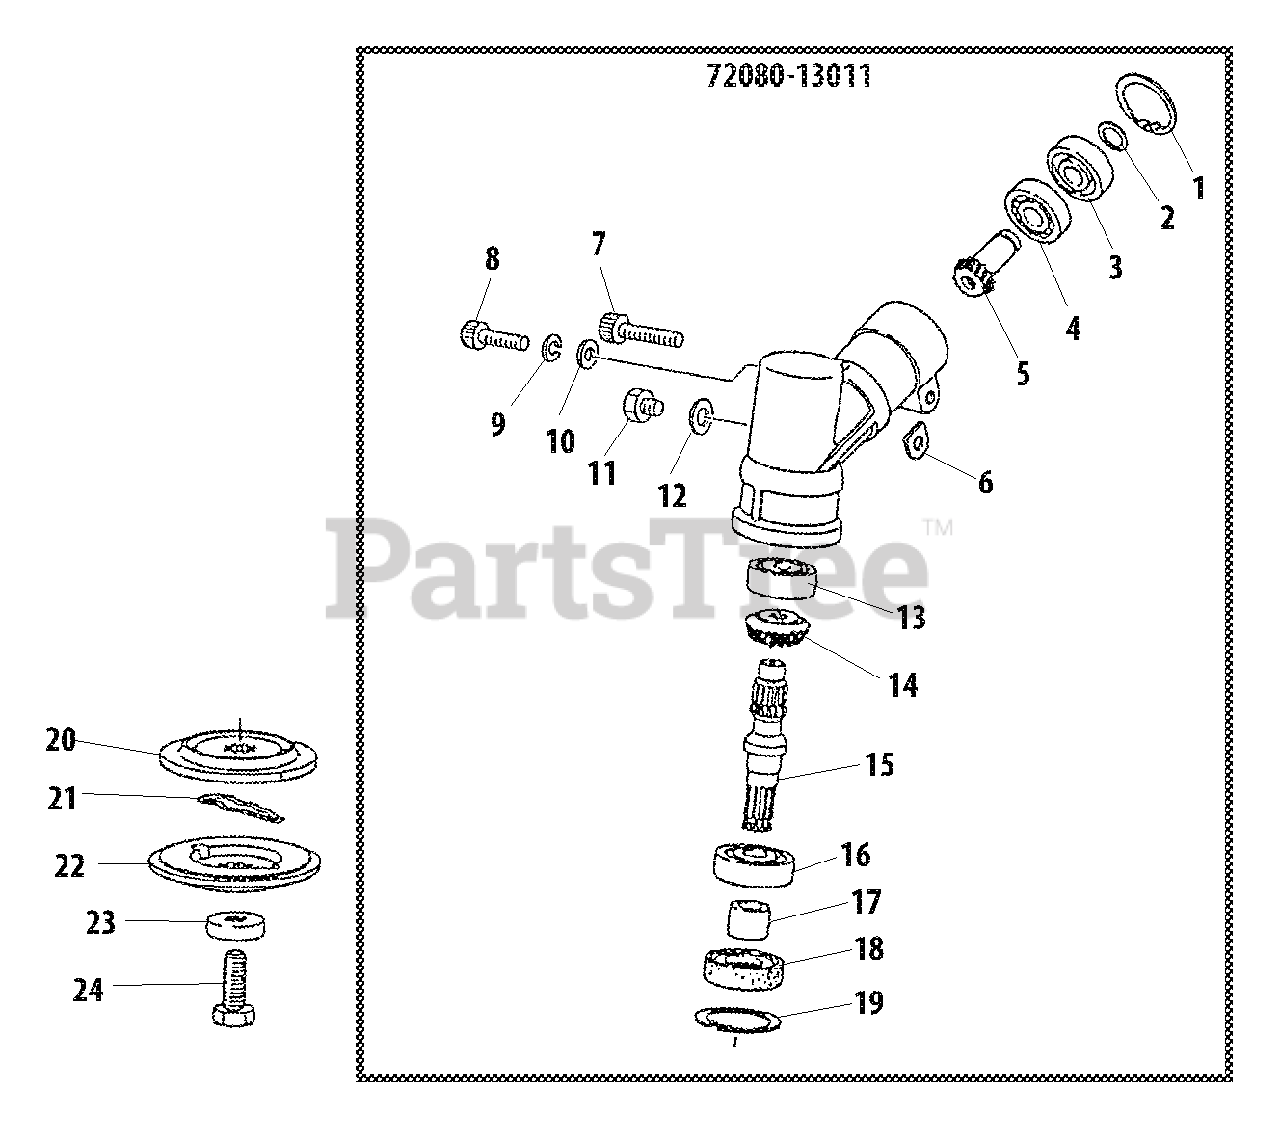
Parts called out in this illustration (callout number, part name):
1	RING, SNAP Ø28
2	RING, SNAP Ø12
3	BEARING, BALL 6001ZZ
4	BEARING, BALL 6001
5	PINION ASSY, BEVEL
6	D-WASHER
7	BOLT M6×28
8	BOLT
9	WASHER, SPRING 6
10	WASHER 6.5×11.5×0.8
11	BOLT M6×10
12	WASHER
13	BEARING, BALL 6000DDU
14	GEAR, BEVEL
15	SHAFT, GEAR
16	BEARING, BALL 6202
17	COLLAR
18	SEAL, OIL
19	RING, SNAP Ø35
20	PLATE, ADAPTOR - UPPER
21	PIN, SLIDE
22	PLATE, ADAPTOR - LOWER
23	GUARD, BOLT
24	BOLT 10×30
72080-13011	GEAR CASE ASSY
